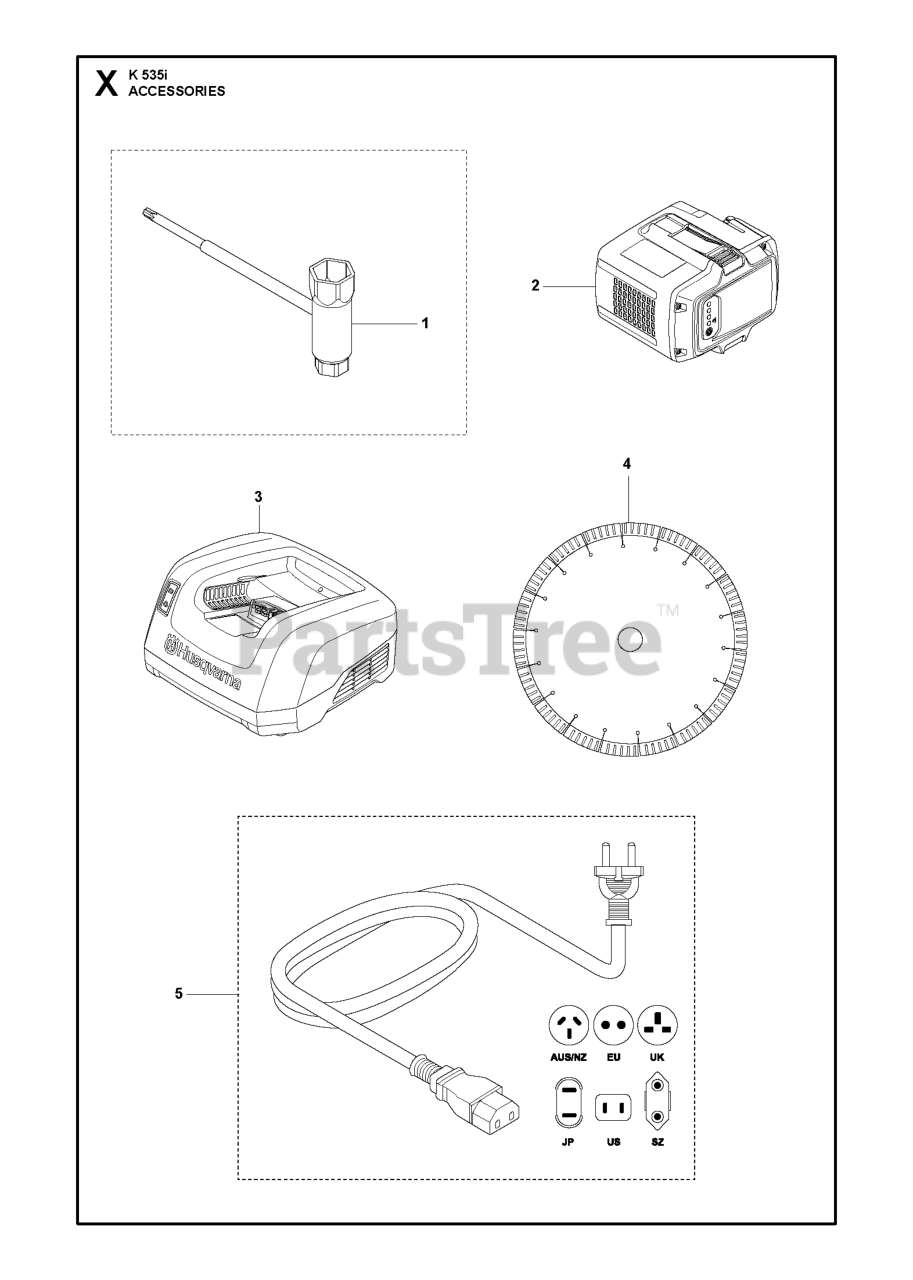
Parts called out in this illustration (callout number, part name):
4	HUS TACTI-CUT PC ABR BLADE 9"
4	HUS TACTI-CUT PC BATT BLADE 9"
4	HUS VARI-CUT PC BATT BLADE 9"
5	CABLE
5	MAIN CABLE
